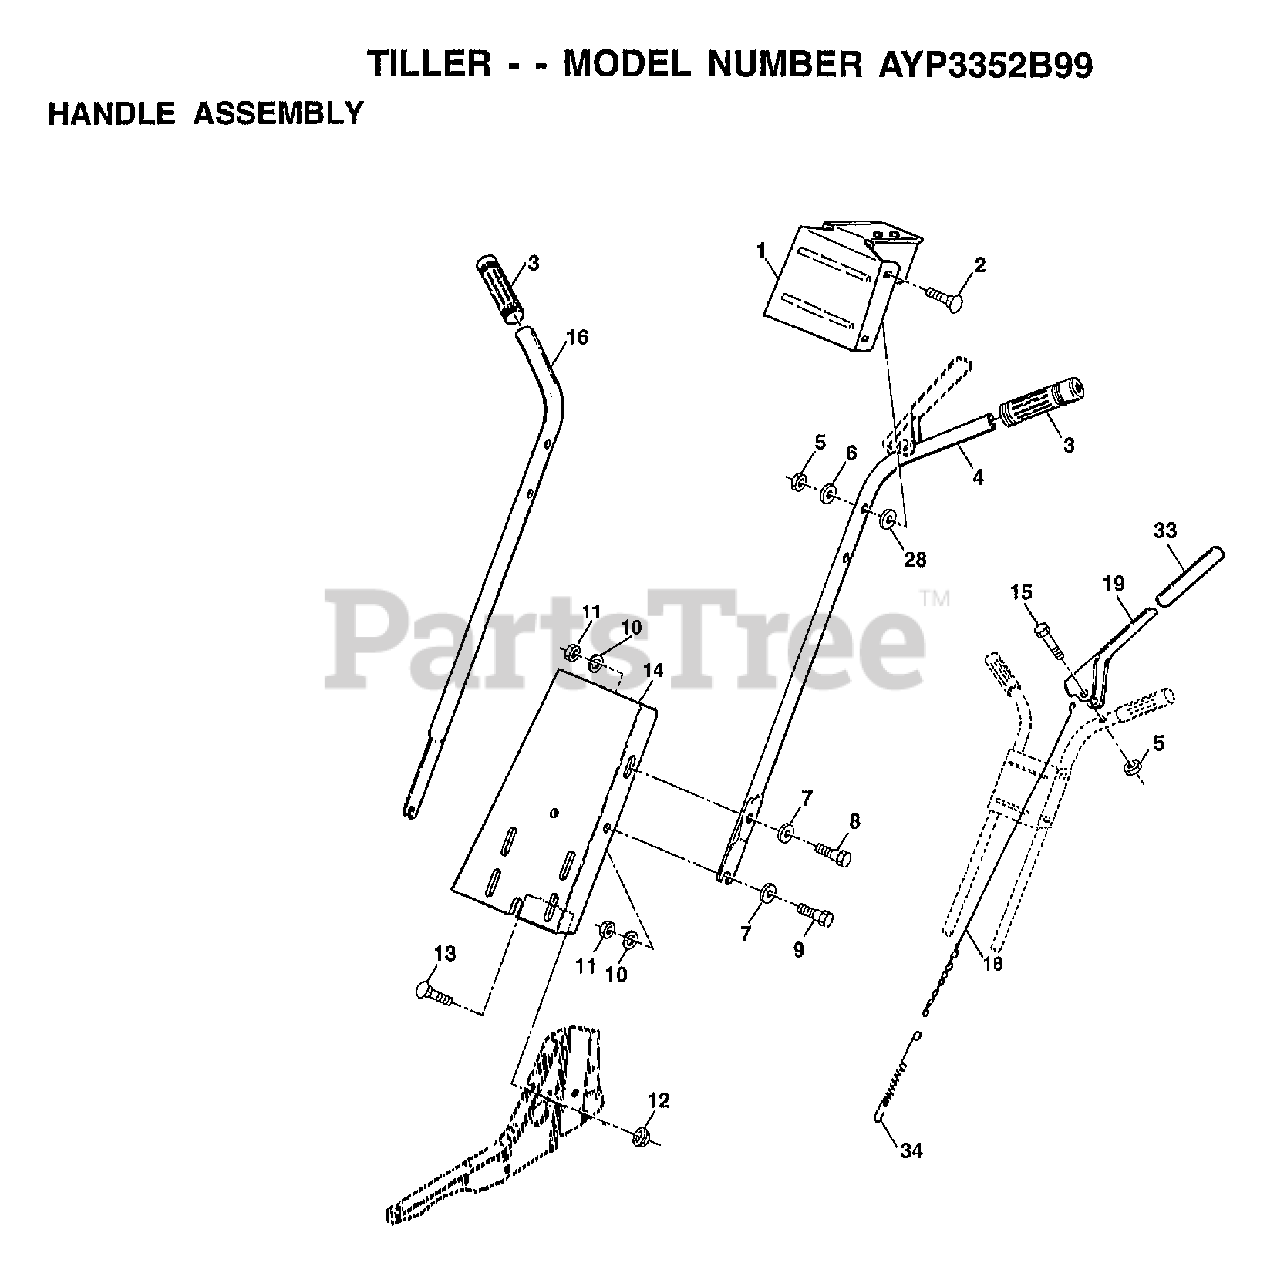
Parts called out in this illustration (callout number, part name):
1	HANDLE BRKT
2	BOLT
4	HANDLE LH
6	WASHER
7	WASHER
9	BOLT
10	LOCKWASHER
11	NUT.HEX.5/16-18
12	NUT
13	BOLT
14	PANEL. HANDLE
15	BOLT.HEX.5/16-1.5
16	HANDLE RH
19	LEVER.CONTROL.TINE
28	WASHER
33	GRIP T
34	SPRING EXT TI
